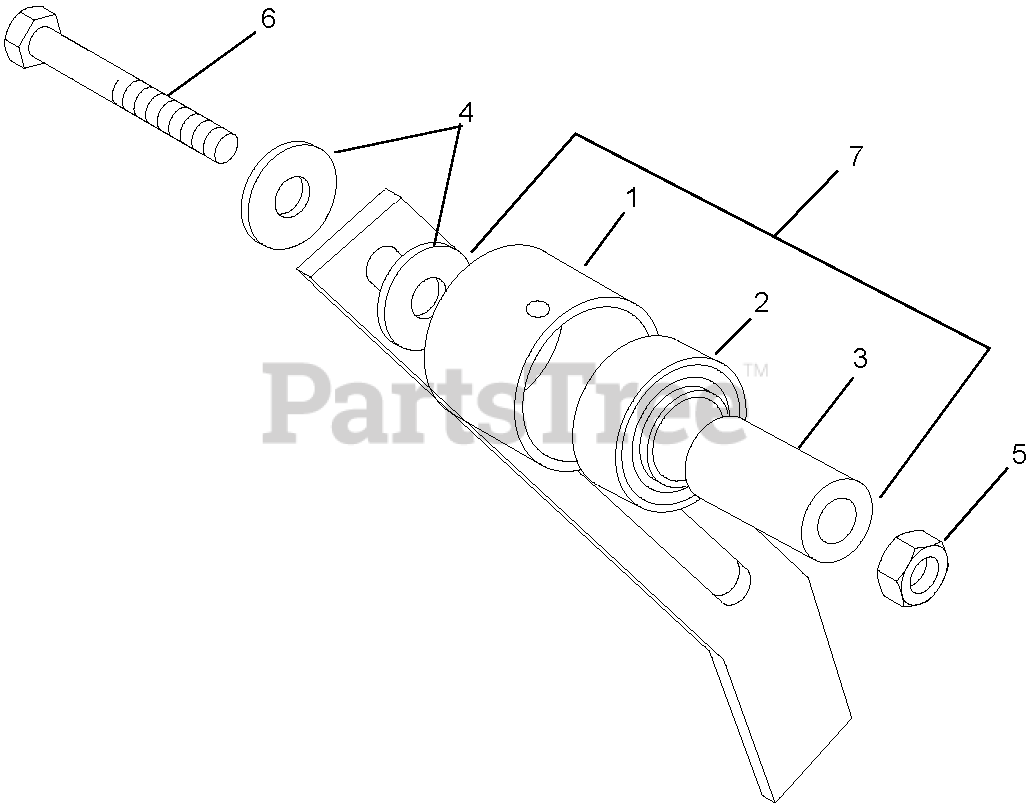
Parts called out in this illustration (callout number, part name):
1	Shell, Idler 2.50"
2	Bearing 1.000 ID x 2.0472 OD
3	Bushing, Idler
4	Washer, Flat .50 SAE
5	Nut, Hex .50-13 Nylock
6	Cap Screw, Hex Head .50-13 x 3.50
7	Idler Assembly 2.50"
